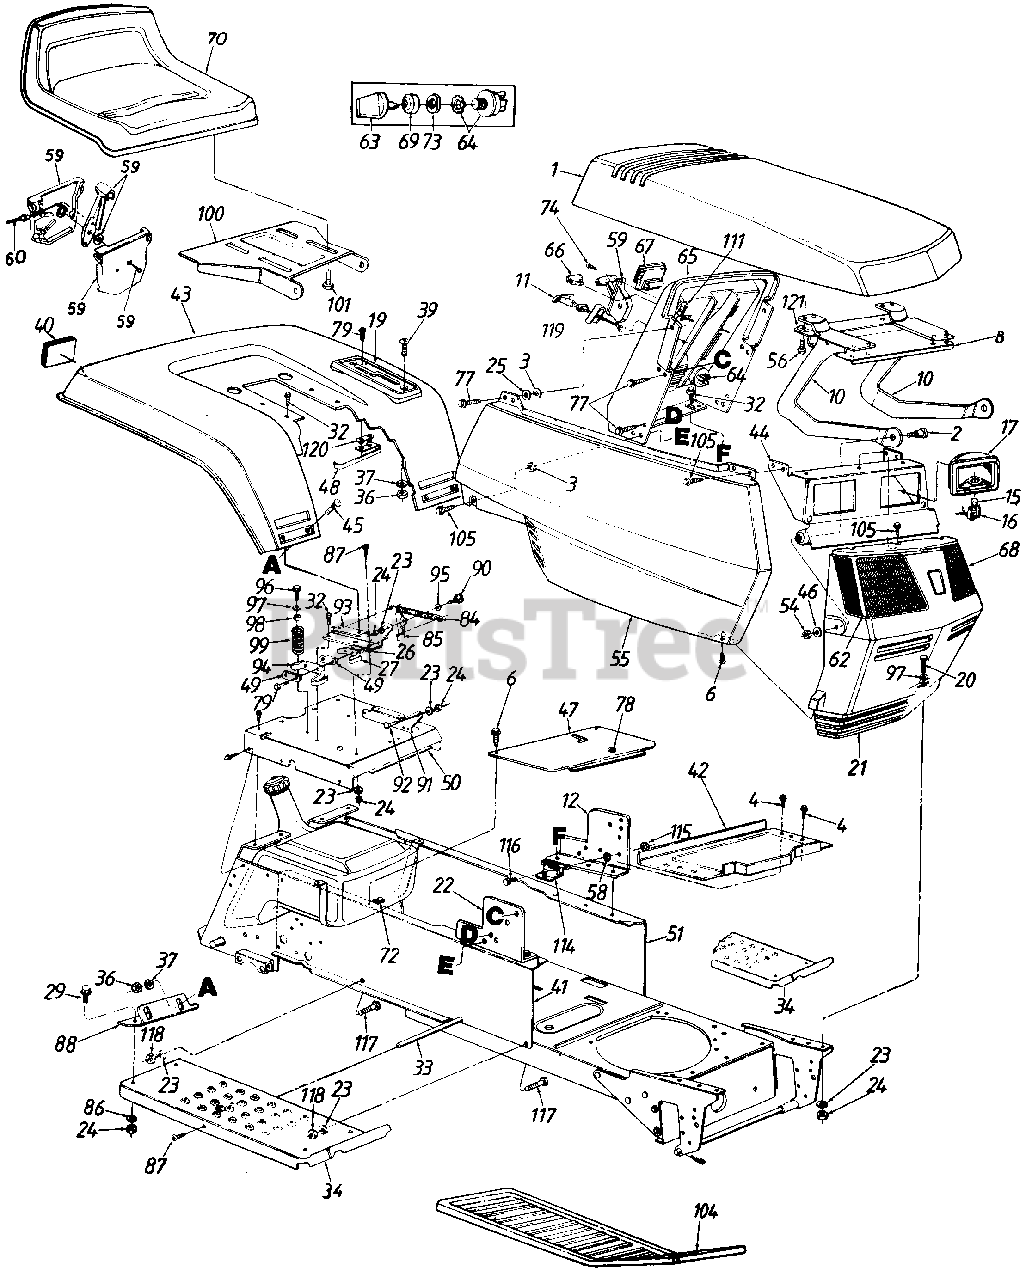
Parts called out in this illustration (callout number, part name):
1	Hood Ass'y.
2	Shld. Bolt .437" Dia. x .35"
3	Bolt Retainer 1/4" I.D.
4	Hex Ab-Tap Scr. 1/4 x .62" Lg.
6	Truss Mach. B-Tap Scr. #10 x .5" Lg.
16	Twist Lock - Lamp Socket
17	Headlight Housing
19	Speed Control Index Brkt.
20	Hex Bolt 5/16-18 x .75" Lg.
21	Grille
24	Hex Nut 5/16-18 Thd.
25	Fl-Wash. 1/4" I.D. x .93" O.D.
26	Insulator Boss Plate
27	Seat Spring Switch
29	Hex Bolt 5/16-18 x 1.0" Lg.
32	Hex Wash. Hd. AB-Tap Scr. 5/16 x .75" Lg.
33	Running Board Rod
37	L-Wash. 1/4" I.D.
39	Truss Mach. Scr. 1/4-20 x 1.0" Lg.
40	Reflector
41	R.H. Side Frame
42	Battery Plate
46	Fl-Wash. .328" I.D. x .68" O.D.
49	Insulator Plate
54	Hex Cent. L-Nut 1/6-18 Thd.
55	Side Panel Ass'y. - R.H.
56	Hex Wash. Hd. B-Tap Scr. 1/4 x .62" Lg.
58	Ext. L-Wash. 1/4" I.D.
59	Throttle Control Box Ass'y.
60	Throttle Control Wire - 35" Lg.
62	Lens - R.H.
63	Ignition Key
64	Ignition Switch
65	Dash Panel
66	Light Switch
67	Ammeter
68	Lens - L.H.
69	Ignition Switch Cap
70	Seat Ass'y.
72	Speed Nut #10 Z
73	Ignition Switch Nut
74	Truss Mach. AB-Tap Scr. #10 x .5 Lg.
77	Hex Wash. Hd. Tap Scr. 1/4 x .75" Lg.
78	Snap Bushing
79	Hex Wash. Hd. AB-Tap Scr. #8 x .50" Lg.
84	Ext. Spring 5.31" Lg.
85	Seat Lift Brkt.
86	Bell-Wash. .345" I.D. x .88" O.D.
87	Truss Machine Scr. 5/16-18 x .75" Lg.
95	Spr.-Wash. .445" I.D.
96	Hex Wash. Hd. Tap Scr. 5/16-18 x .75" Lg.
97	Fl-Wash. .344" I.D. x 1" O.D.
98	Bushing
99	Compression Spring
101	Hex Tap Scr. 3/8-16 x .75"
104	Foot Pad
105	Hex Tap Scr. 1/4-20 x .5" Lg.
111	Speed Nut 1/4-20 Thd.
114	Solenoid
115	Hex Sems Nut 1/4-20 Thd.
116	Hex Bolt 1/4-20 x .5" Lg.
117	Rib Neck Bolt 5/16-24 x .75" Lg.
118	Hex Nut 5/16-24 Thd.
119	Retainer Clip
120	Insulator Nut Plate
